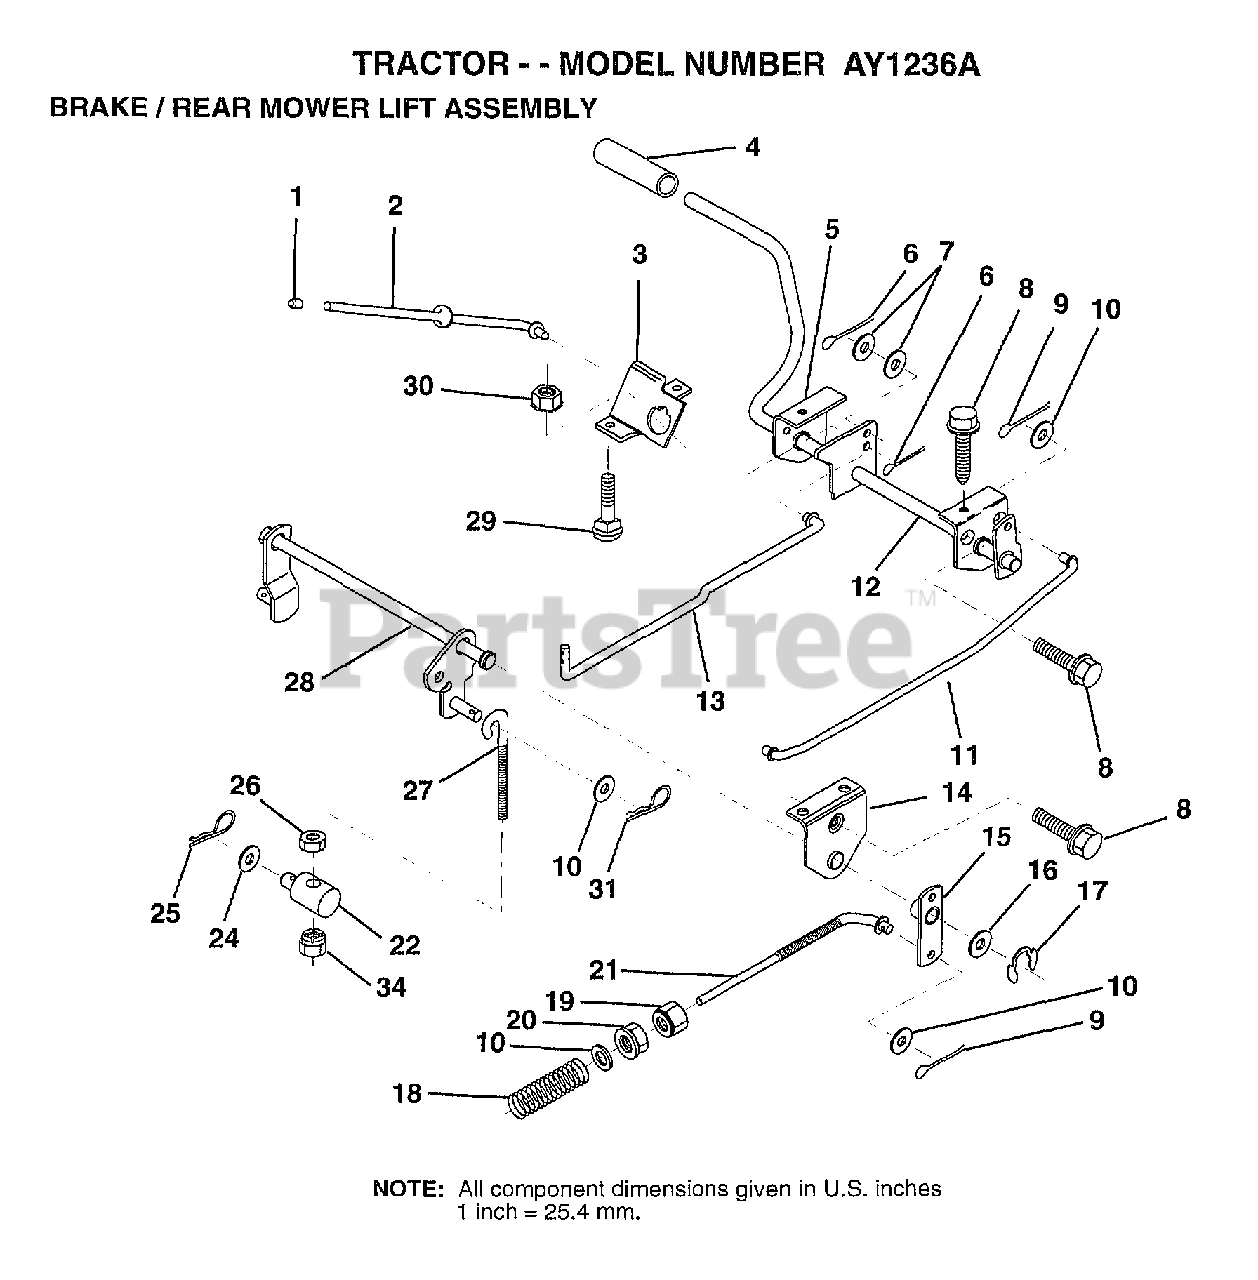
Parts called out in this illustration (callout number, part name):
1	PLUNGER CAP T
2	"ROD,PARK BRAKE"
3	"BRKT,PARK BRAKE"
4	FOOT PEDAL COVER
5	"BRKT,CLU PEDAL LH"
7	WASHER
8	SCREW LT
9	COTTER PIN
10	WASHER
11	"ROD,FRT BRAKE"
12	PEDAL ASM CL/BK36
13	"ROD,CLUTCH"
14	"BRKT,LIFT SHAFT"
15	PVT BRAKE ARM ASM
16	WASHER T
17	KLIP RING
18	SPRING ROD BRAKE
19	NUT
20	NUT
22	TRUNNION.LIFT.
24	WASHER
25	SPRING.RETAINER
26	LOCKNUT
27	"LINK, MOWER REAR"
28	LIFT ASM MOW REAR
31	RETAINER.SPRING
